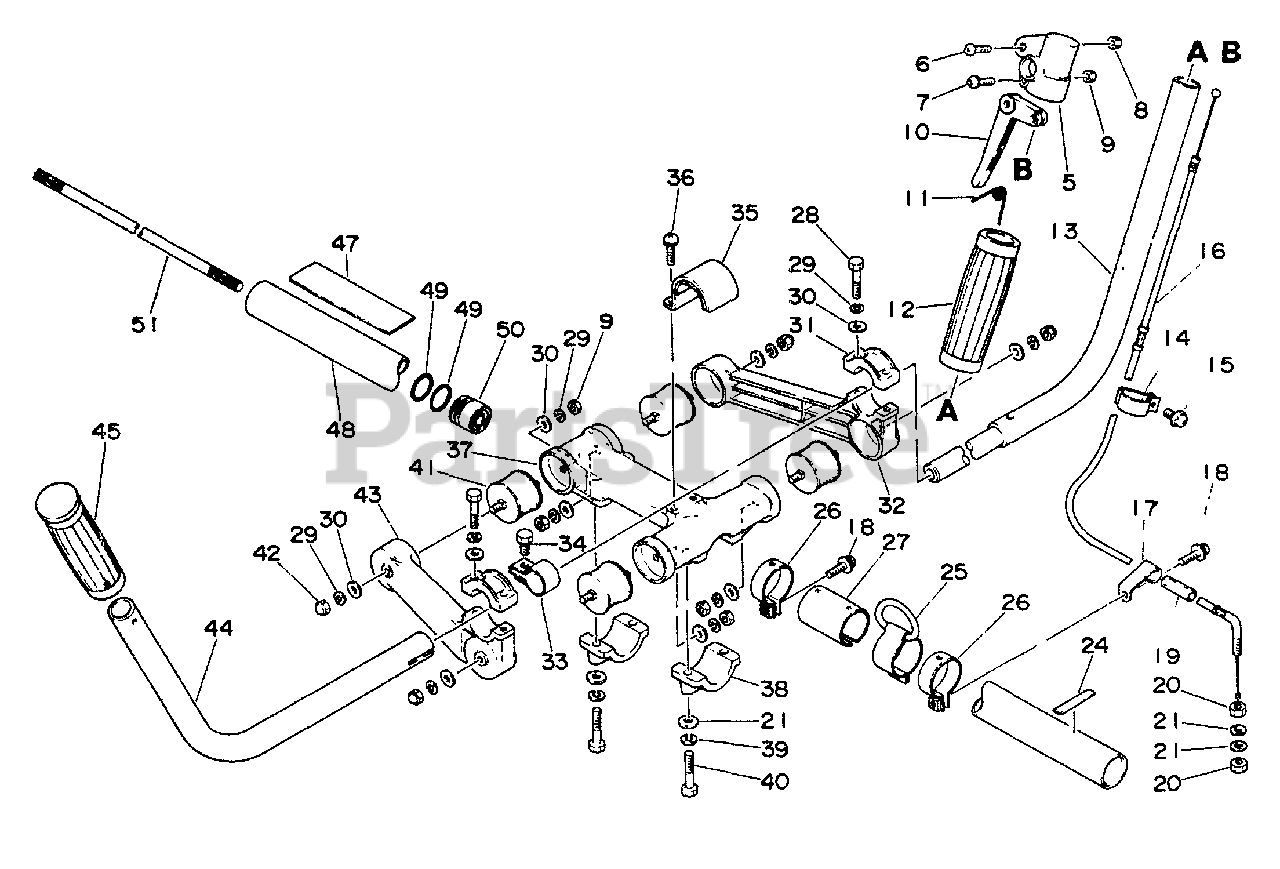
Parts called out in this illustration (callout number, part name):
5	BRACKET, TRIGGER
7	SCREW 5×25
8	LOCKNUT - 5
9	NUT M5
10	TRIGGER, THROTTLE
12	GRIP, HANDLE
14	CLAMP
15	SCREW 5×12
16	CABLE, THROTTLE
18	SCREW 5×14
19	TUBE, VINYL
21	WASHER 6.5×11.5×0.8
24	LABEL - ALIGNMENT
25	HOOK
26	CLAMP
27	COLLAR
28	BOLT - 5×25
29	WASHER, SPRING 5
30	WASHER, FLAT 5.5×10×0.8
31	RETAINER
32	ARM, RETAINER - RIGHT
33	BAND
34	BOLT - 6×12
35	PLATE
36	SCREW 5×14
37	HOLDER, D.S. HOUSING
38	HOLDER
39	WASHER, SPRING 6
40	BOLT - 6×30
41	CUSHION
42	NUT - 5 -- CAP
43	ARM, HANDLE - LEFT
44	HANDLE, FRONT
45	GRIP, HANDLE
47	LABEL - CAUTION
48	MAIN PIPE ASSY
50	BUSHING
51	DRIVESHAFT
